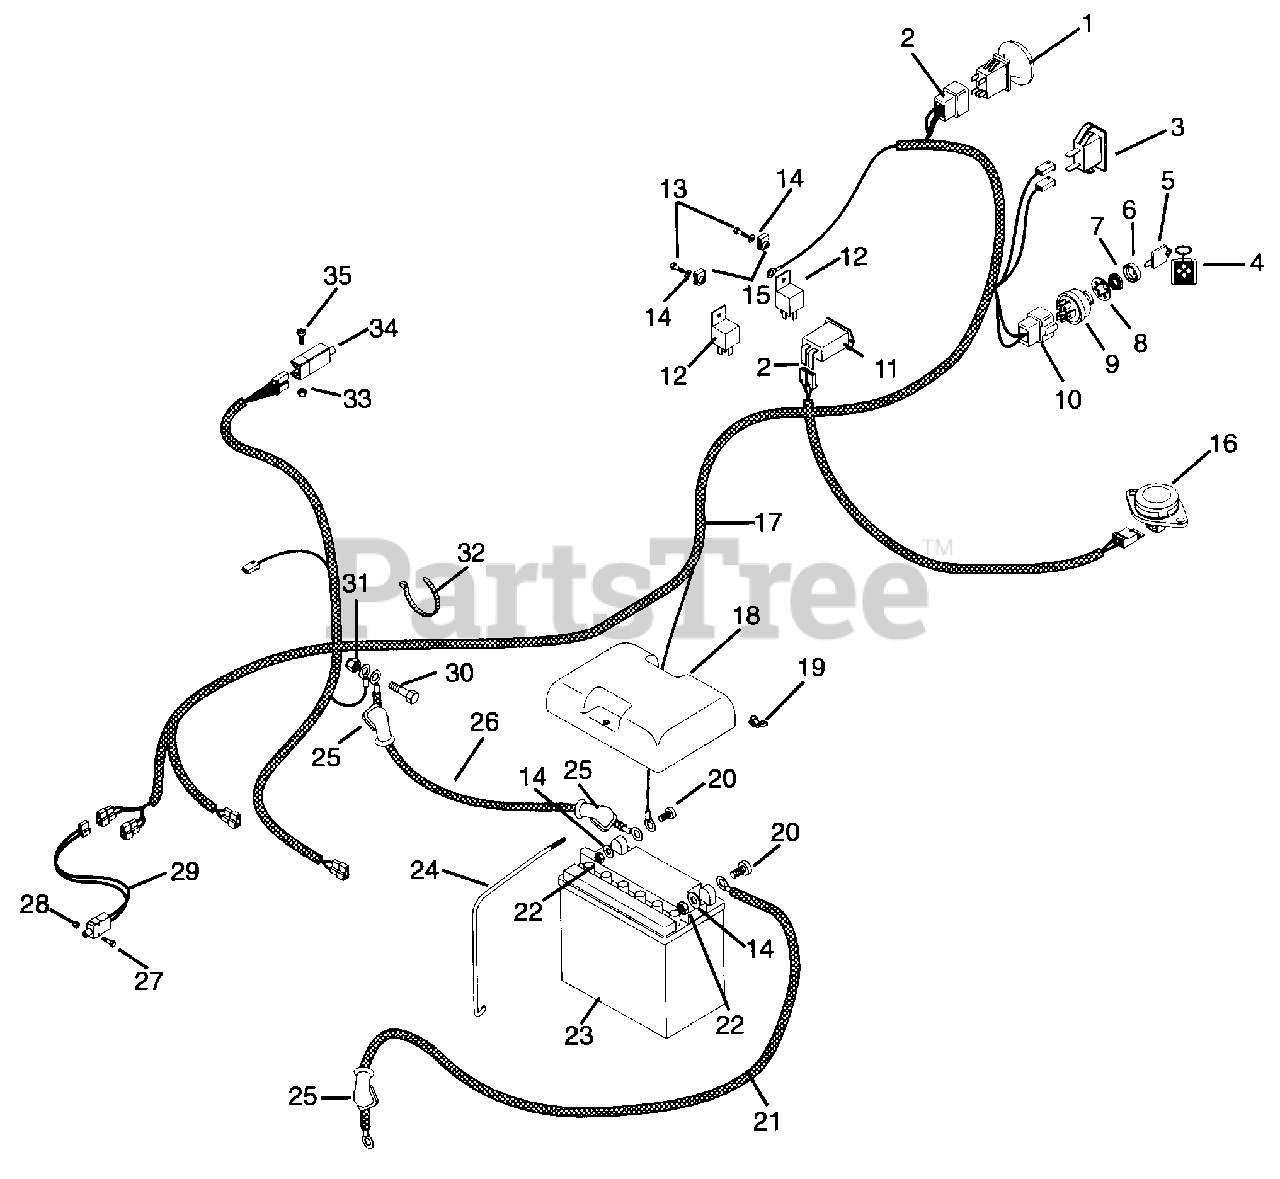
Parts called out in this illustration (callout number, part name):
1	Switch, Clutch with Retainer Ring
2	Terminal
3	Light, Indicator
4	Key Chain
5	Ignition Switch Key
6	Cap-Ignition Switch
7	Nut-Panel .562-24
8	Washer-Lock-Internal .563 x .040
9	Key Switch
10	Connector
11	Hour Meter
12	Relay
13	Screw-Machine .31-18 x.625 Left Hand
14	Washer-Flat-Steel .281 x .620 x .065
15	Nut-Speed .25-20
16	Seat Switch
17	Wire Harness
18	Cover, Battery
19	Nut-Locking-Wing .250-20
20	Bolt-Hex .25-20 x .75 Grade 5
21	Cable, Starter
22	Nut-Hex .25-20
23	Battery
24	Rod, Battery
25	Boot, Insulator
26	Cable, Negative Battery
27	Screw-Machine 6-32 x .75
28	Nut-Locking-Nylon 6-32 W/Insrt
29	Switch
30	Bolt-Hex .31-18 x 1.00 Grade 5
31	Nut-Locking-Center .31-18
32	Tie, Wrap, Black
33	Nut-Locking Nylon 10-24 W/Insrt
34	Switch, Interlock
35	Screw-Machine .38 x 7.0
